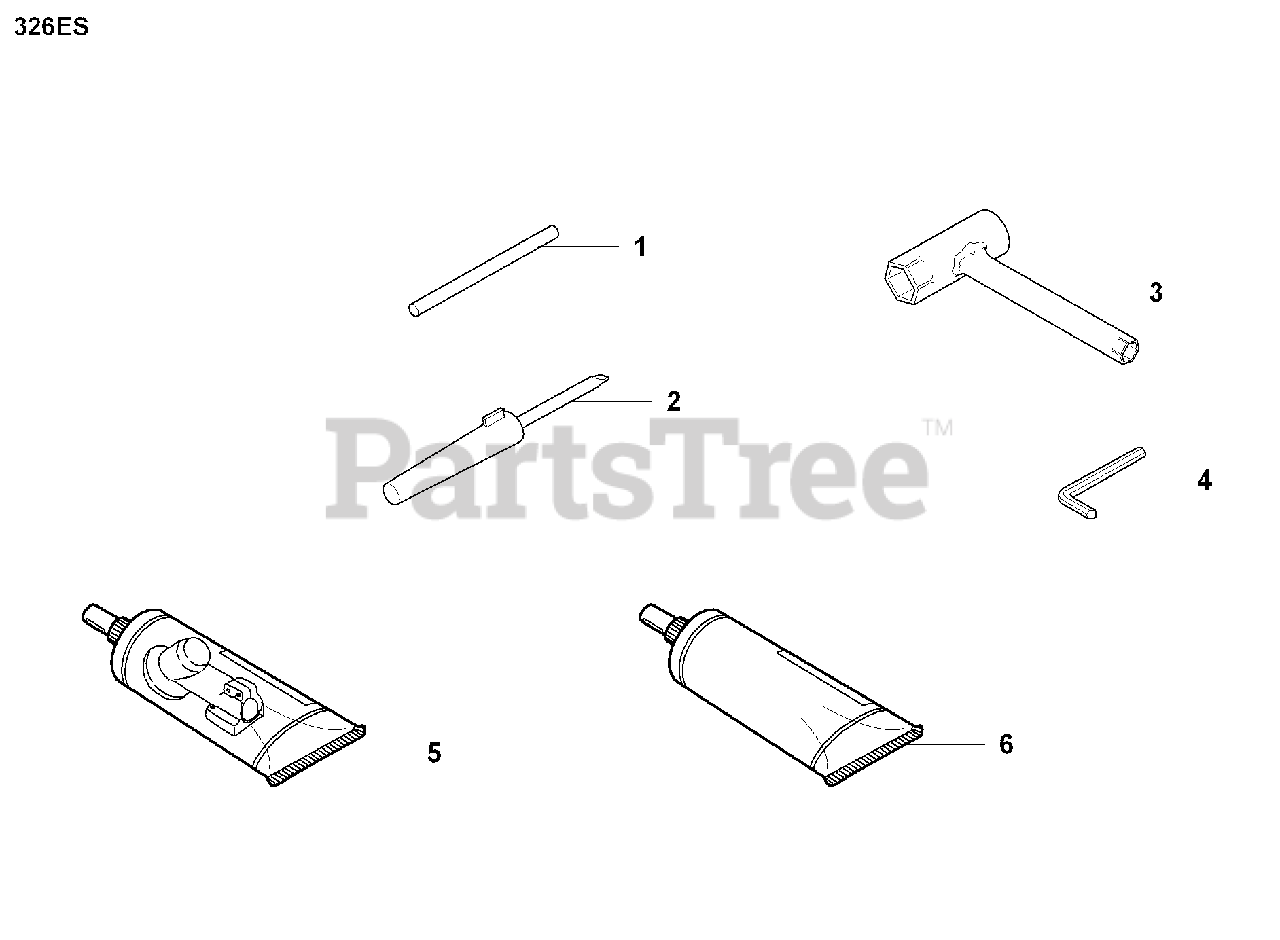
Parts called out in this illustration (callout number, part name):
1	LOCKING PIN
2	SCREWDRIVER
3	COMBI WRENCH
4	L-KEY WRENCH
5	BEVEL GEAR GREASE
